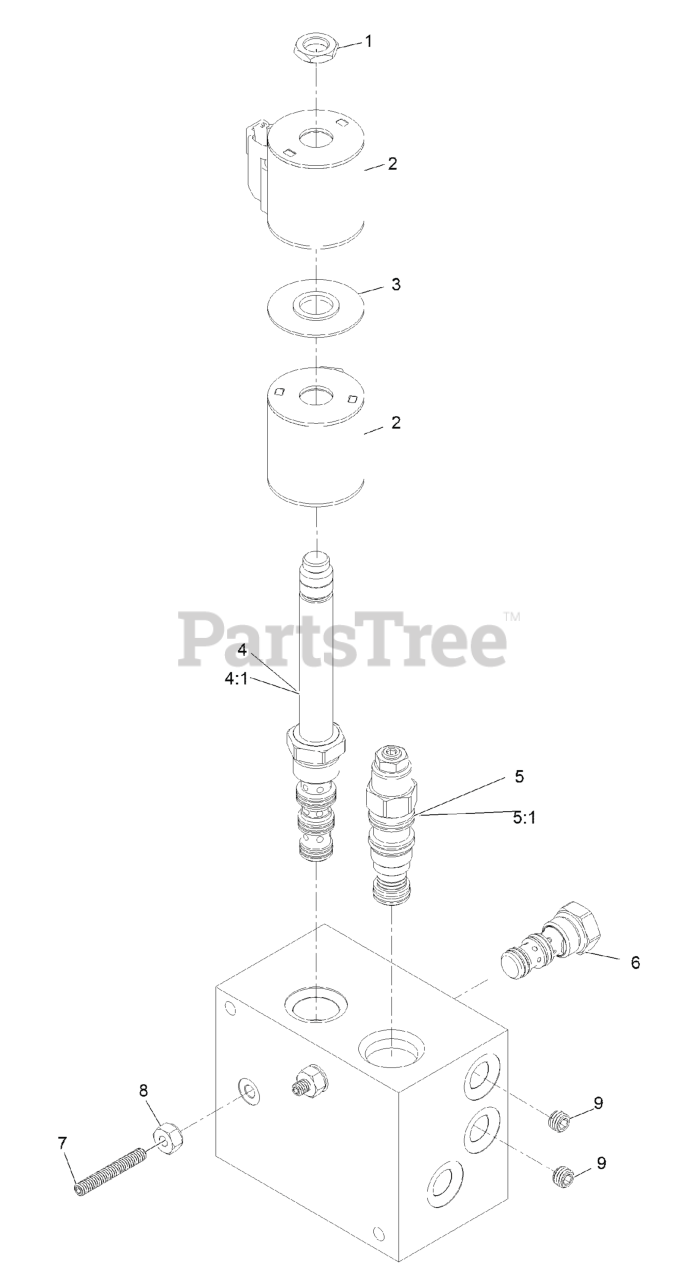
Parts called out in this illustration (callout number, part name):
1	NUT-COIL
2	COIL-12V
3	Spacer-E Coil
4	Solenoid Valve ASM
4:1	SPOOL VALVE SEAL KIT
5	VALVE-COUNTERBALANCE
5:1	Seal Kit
6	Valve-Check, Po
7	SCREW-SET
8	Nut-Sealing, Hex
9	Plug-Orifice (0.020)
